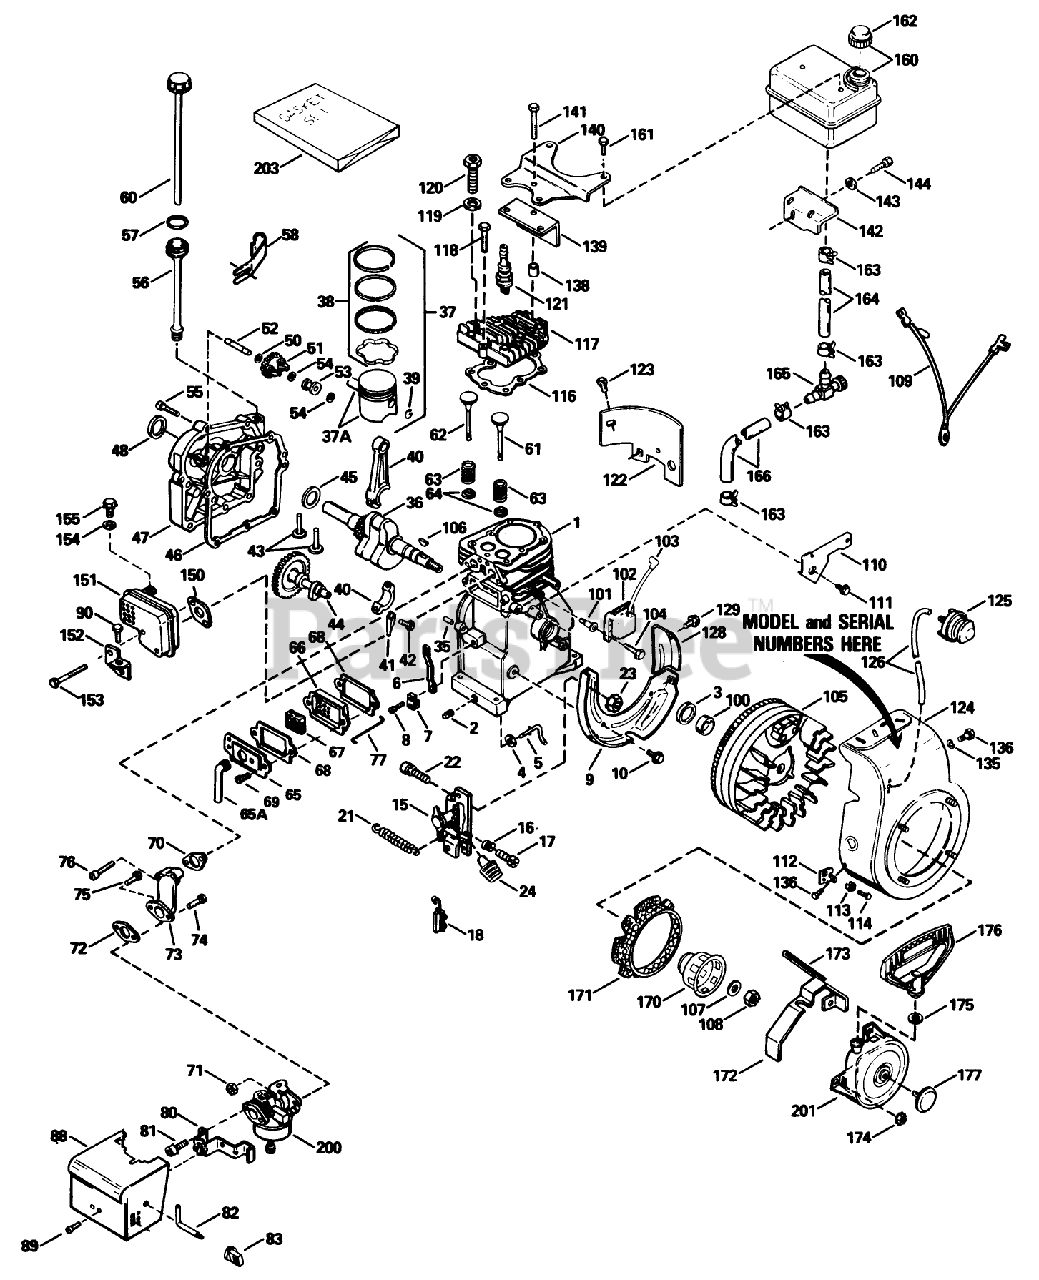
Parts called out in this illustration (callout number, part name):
1	Cylinder Assembly (Incl. Ref. #2, 3 4)
2	Plug-Drain, Oil (SQH 1/4-18)
3	Seal-Oil
4	Washer-Flat
5	Rod-Governor
6	Lever-Governor
7	Clamp-Lever, Governor
8	Screw
9	Baffle-Blower Housing
10	Screw (1/4-20x19/32)
15	Control Assembly, Speed (Incl. Ref. #155 thru 158 160)
16	Spring-Compression
17	Screw
18	Terminal
21	Spring-Extension
22	Screw
23	Nut-Lock
24	Knob-Control
35	Pin-Dowel
36	Crankshaft ASM
37	Piston, Pin Ring Assy., (Incl. Ref. #15 16) (Std.)
37	Piston, Pin Ring Assy., (Incl. Ref. #15 16) (.010 Oversize)
37	Piston, Pin Ring Assy., (Incl. Ref. #15 16) (.020 Oversize)
37A	Piston Pin Assy. (Incl. Ref. #16) (Std.)
37A	Piston Pin Assy., (Incl. Ref. #16) (.010 Oversize)
37A	Piston Pin Assy. (Incl. Ref. #16) (.020 Oversize)
38	Ring Set-Piston Std.
38	Ring Set-Piston .010 oversize
38	Ring Set-Piston .020 oversize
39	Ring-Retaining, Piston Pin
40	Rod Assembly, Connecting (Incl. Nos. 17 18)
41	Dipper-Oil
42	Bolt-Rod, Connecting
43	Lifter-Valve
44	Camshaft
45	Washer-Thrust
46	Gasket-Cylinder Cover
47	Cover-Cylinder (Incl. Ref. #59 72)
48	Seal-Oil
50	Washer-Flat
51	Governor Gear ASM
52	Shaft-Governor
53	Spool-Governor
54	Ring-Retaining
55	Screw (1/4-20 x 1-1/4)
56	Tube-Fill, Oil
57	O-Ring
58	Clip-Tube, Fill
60	Dipstick
61	Valve, Exhaust (Std.)(Incl. No. 40)
61	Valve, Intake (1/32" oversize)(Incl. No. 40)
62	Valve-Intake Standard (Incl. Ref. #151)
62	Valve-Intake 1/32" oversize (Incl. Ref. #151)
63	Spring-Valve
64	Cap-Valve, Spring
65	Cover-Breather
65A	Tube-Breather
66	Body-Breather
67	Element-Breather
68	Gasket-Breather
69	Screw
70	Gasket-Intake
71	Nut and Lock Washer (1/4-28)
72	Gasket
73	Pipe-Intake
75	Screw (1/4-28 x 1-11/16)
76	Screw (1/4-20 x 1-19/32)
77	Link-Governor to Throttle
80	Bracket-Choke
81	Screw (10-32 x 1/2)
82	Rod-Choke
83	Knob-Control
88	Cover-Carburetor
89	Screw (8-32 X 5/16)
90	Screw (10-24 x 3/8)
100	Spacer
102	Solid State
103	Cover-Spark Plug
104	Screw
105	CLAMP
106	Key-Flywheel
107	Washer-Belleville
108	Nut-Flywheel
109	Wire-Ground
110	Bracket-Hold Down
111	Screw (10-24 x 9/16)
112	Bracket
113	Grommet
114	Screw (8-32 x 3/8)
116	Oil Fill Tube
117	Head Cylinder
118	Screw (5/16-18x1-1/2)
119	Washer-Flat
120	Screw ( 5/16-18 x 1-1/2)
121	Spark Plug-Resistor (R J19 L M)
122	Extension-Blower
123	Screw
124	Housing-Blower
125	Primer-Asm
126	Line-Primer
128	Baffle-Extension
129	Screw-Hex Washer Hd.
135	Washer
136	Screw
138	pacer
139	Baffle-Heat
140	Plate-Fuel Tank
141	Screw (5/16-18 X 2)
142	Bracket-Fuel Tank
143	Washer
144	Screw Assembly
150	Gasket-Exhaust
151	Muffler
152	Bracket-Cover, Carburetor
153	Screw-Fil. Hd.
154	Washer
155	Screw
160	481-1261 SENATOR TI
161	Screw (1/4-15x7/8)
162	Cap, Fuel
163	Clamp-Line, Fuel
164	Line-Fuel (8.62)
165	Valve-Shut Off
166	Line-Fuel
170	Cup-Starter
171	Screen-Starter
172	Guard-Starter
173	Seal, Snowguard
174	Nut and Lock Washer (1/4-28)
175	Washer
176	Handle-Starter, Mitten Grip
177	Plug-Starter
200	Carburetor (Incl. Ref. #87)
201	Starter-Rewind
203	Gasket Set (Incl. Items Marked *)
